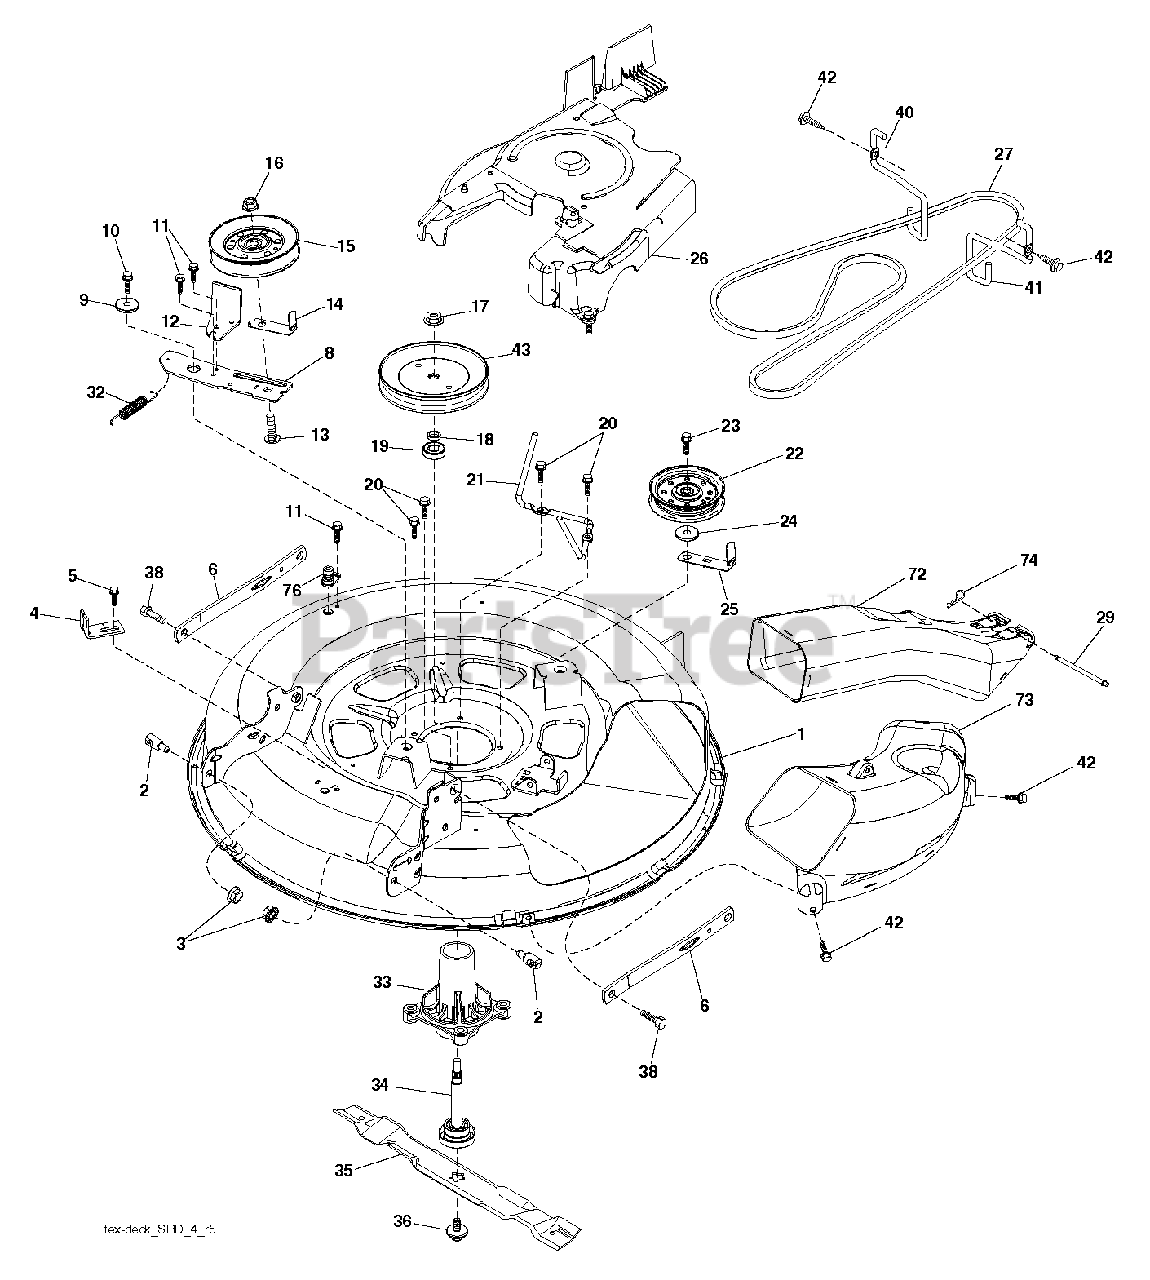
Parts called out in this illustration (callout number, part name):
2	STUD.FASTNER.W/ANTI-ROTATE
3	NUT LOCK HEX FLANGE 5/16-18
5	BOLT.5/16HEX.WHS.HD
6	ARMS.SUSP.MOWER.REAR.SRD
9	SPACER.RETAINER
10	SCREW 3/8-16X1
11	SCREW.1/4-20X5/8
12	ARM BRAKE MOWER RH
13	BOLT.3/8-16X1.50
14	KEEPER, BELT IDLER
15	PULLEY.IDLER.4.25
16	NUT LOCK FLG 3/8-16 UNC
17	NUT.FLANGE.LOCK.TOP
18	WASHER.SPACER.MANDREL
20	SCREW, WASHER HEAD
22	PULLEY.IDLER.FLAT.46.PR.DR.
23	SCREW LT
27	V-BELT.DRIVE.MOWER.30"
32	SPRING.MOWER.DRIVE.ELECTRIC
33	HOUSING MANDREL
34	SHAFT.ASM.MDRL.N/GREASE.38
35	BLADE.MOWER.BAGGING.30"
36	BOLT.WASHER.ASM.7/16-2
38	BOLT.SHOULDER
42	SCREW, 3/8-16X3/4
43	PULLEY, MANDREL 6.5 PD
74	RETAINER-SPRNG RB
76	PORT.WASHOUT
